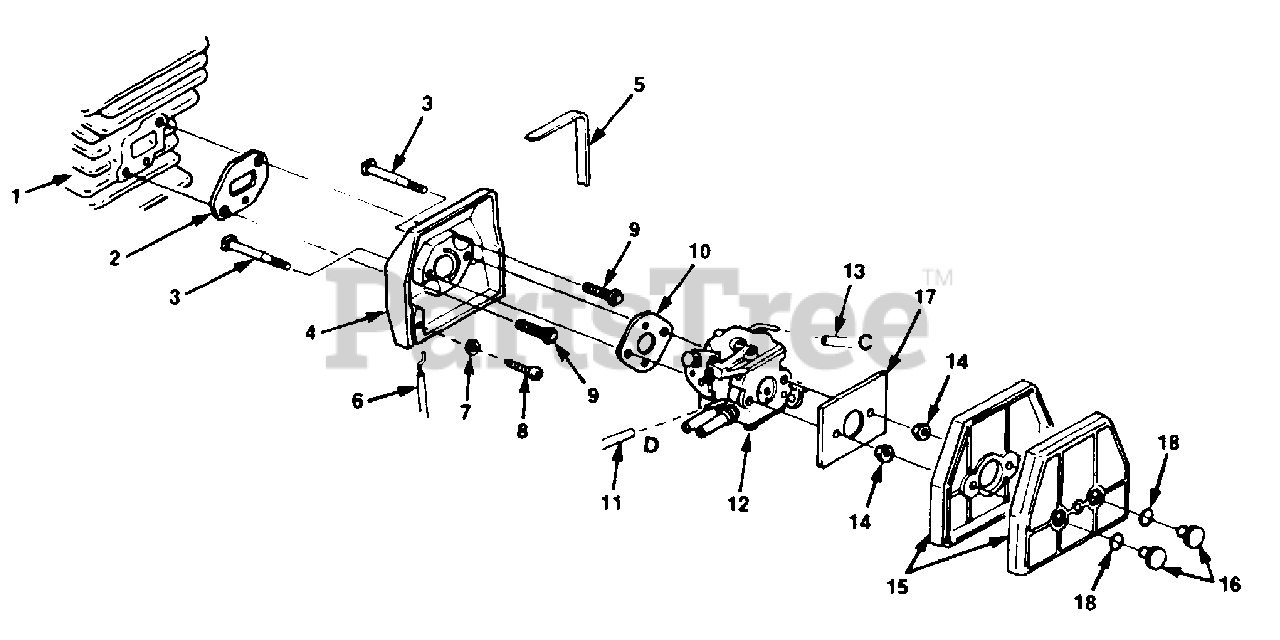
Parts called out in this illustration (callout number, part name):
1	CYLINDER
2	GASKET- Carburetor spacer
3	SCREW- Carburetor spacer
4	SPACER- Carburetor
5	FOAM- Adhesive
6	CABLE- Throttle
8	SCREW- Thread forming
9	SCREW- Mach. hex hd.
10	GASKET- Carburetor
11	TUBING- Rubber
12	CARBURETOR- Walbro (WT-185)
13	TUBING- Rubber
14	NUT- Hex (8/32)
15	AIR FILTER ASSEMBLY
16	NUT- Retainer
17	RETAINER- Air filter
